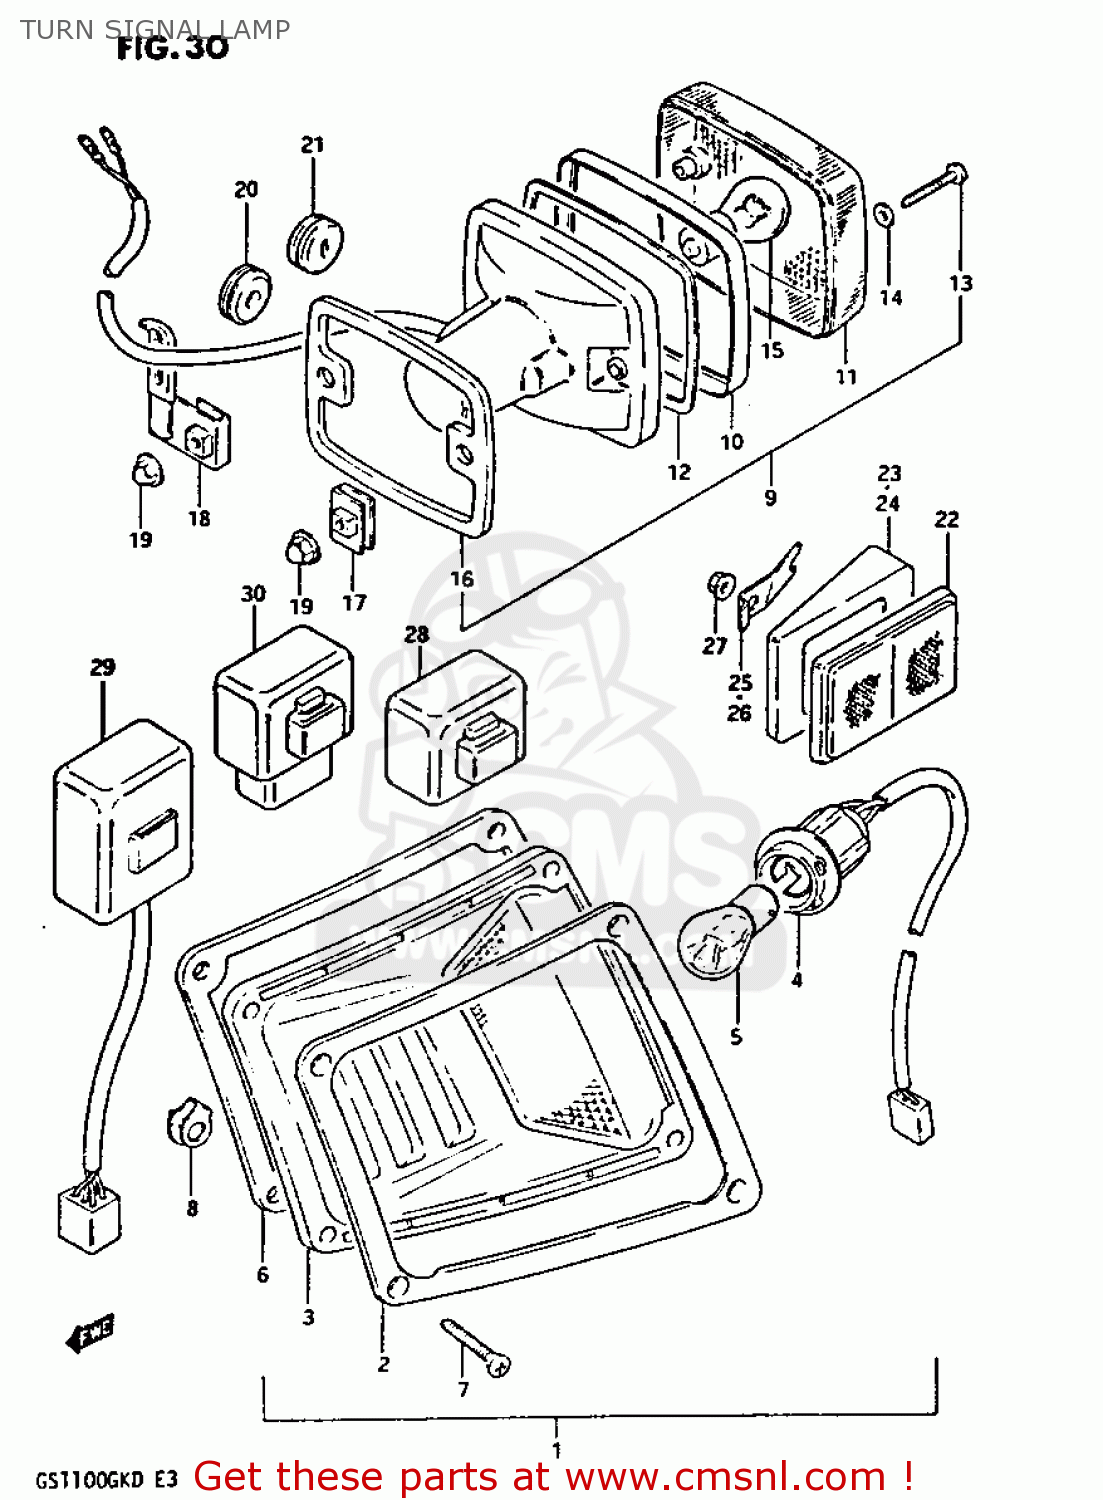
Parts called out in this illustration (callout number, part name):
1	LAMP ASSEMBLY,FRONT TURN SIGNAL
2	RIM,FRONT TURN SIGNAL LAMP
3	COVER,COWLING,LEFT
4	SOCKET & CORD
5	BULB(12V23W)
6	GASKET,TURN SIGNAL LAMP
7	SCREW,TURN SIGNAL LAMP
8	PLATE
9	LAMP ASSEMBLY,REAR TURN SIGNAL
10	RIM
11	LENS,TURN SIGNAL
12	GASKET (NAS)
13	BOLT
14	GASKET (NAS)
15	BULB(12V23W,STANLEY,A4577A)
16	GASKET
17	PLATE,RR TURN SIGNAL
18	CUSHION
19	NUT 4MM
20	GROMMET
21	GROMMET,TURN SIGNAL LAMP
22	REFLEX REFLECTOR,RR
23	SPACER
24	SPACER
25	WASHER,RIGHT
26	WASHER,REFLECTOR LH
27	NUT
28	RELAY ASSY,TURNSIGNAL
29	UNIT,TURN SIGNAL CONTROL
30	UNIT,TURN SIGNAL CONTROL
